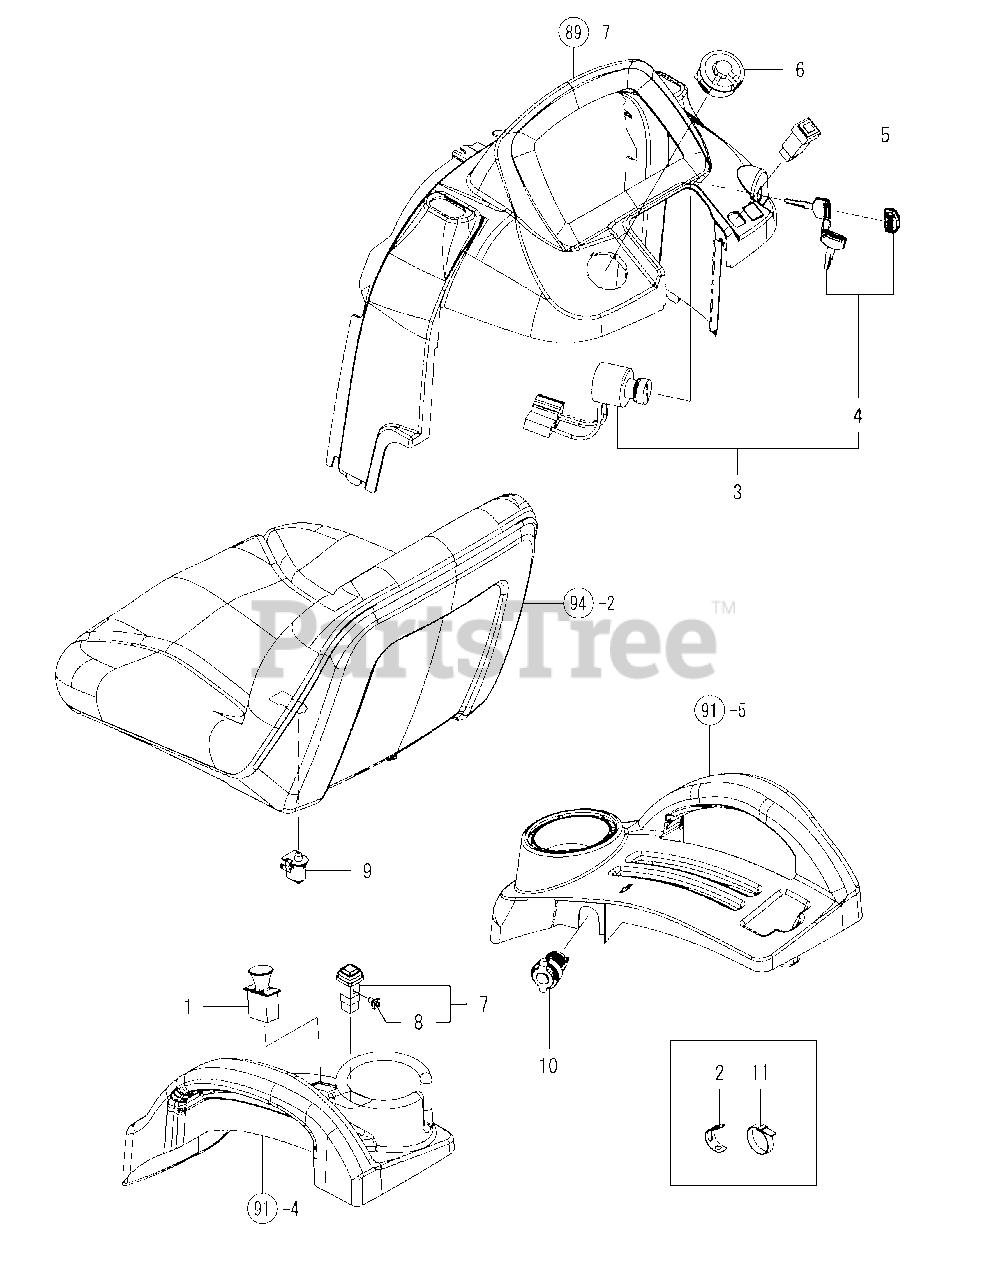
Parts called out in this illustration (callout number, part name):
2	CLAMP, WIRE HARNESS
3	SWITCH ASSY, STARTER
6	SWITCH,COMBINATION
9	SWITCH,SEAT, DELTA, AS
10	DC POWER OUTLET
